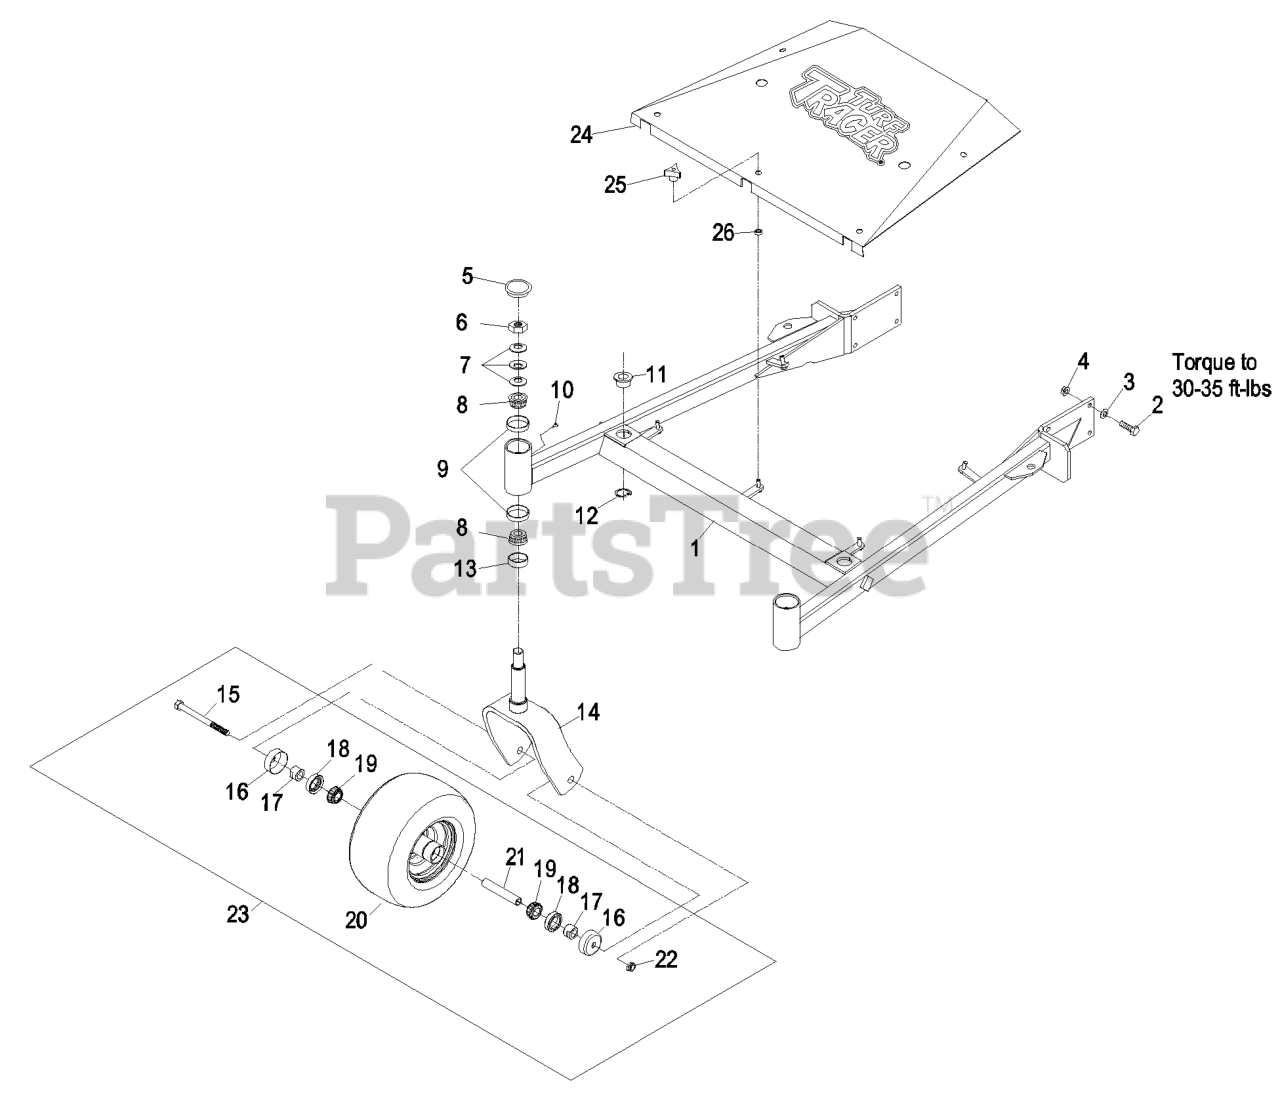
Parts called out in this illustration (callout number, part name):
1	ASM,524 FMD DK SUPPORT,SE
2	SCREW-HH
3	WASHER-BELLEVILLE
4	NUT-HHF, WHIZ
5	CAP-GREASE
6	NUT-LOCK, NI
7	WASHER-BELLVILLE
8	Cone-Bearing Tapered Roller
9	CUP-BEARING
11	BUSHING-DECK
12	RING-RETAINING
13	SEAL-GREASE
14	WLD, CASTER FORK
15	SCREW-HH
16	GUARD-SEAL
17	SPACER-NUT
18	SEAL-CASTER
19	BEARING-CONE, TAPERED ROLLER
22	NUT-HEX
23	ASM,WHEEL&BEARINGS
25	KNOB-3 PRONG
